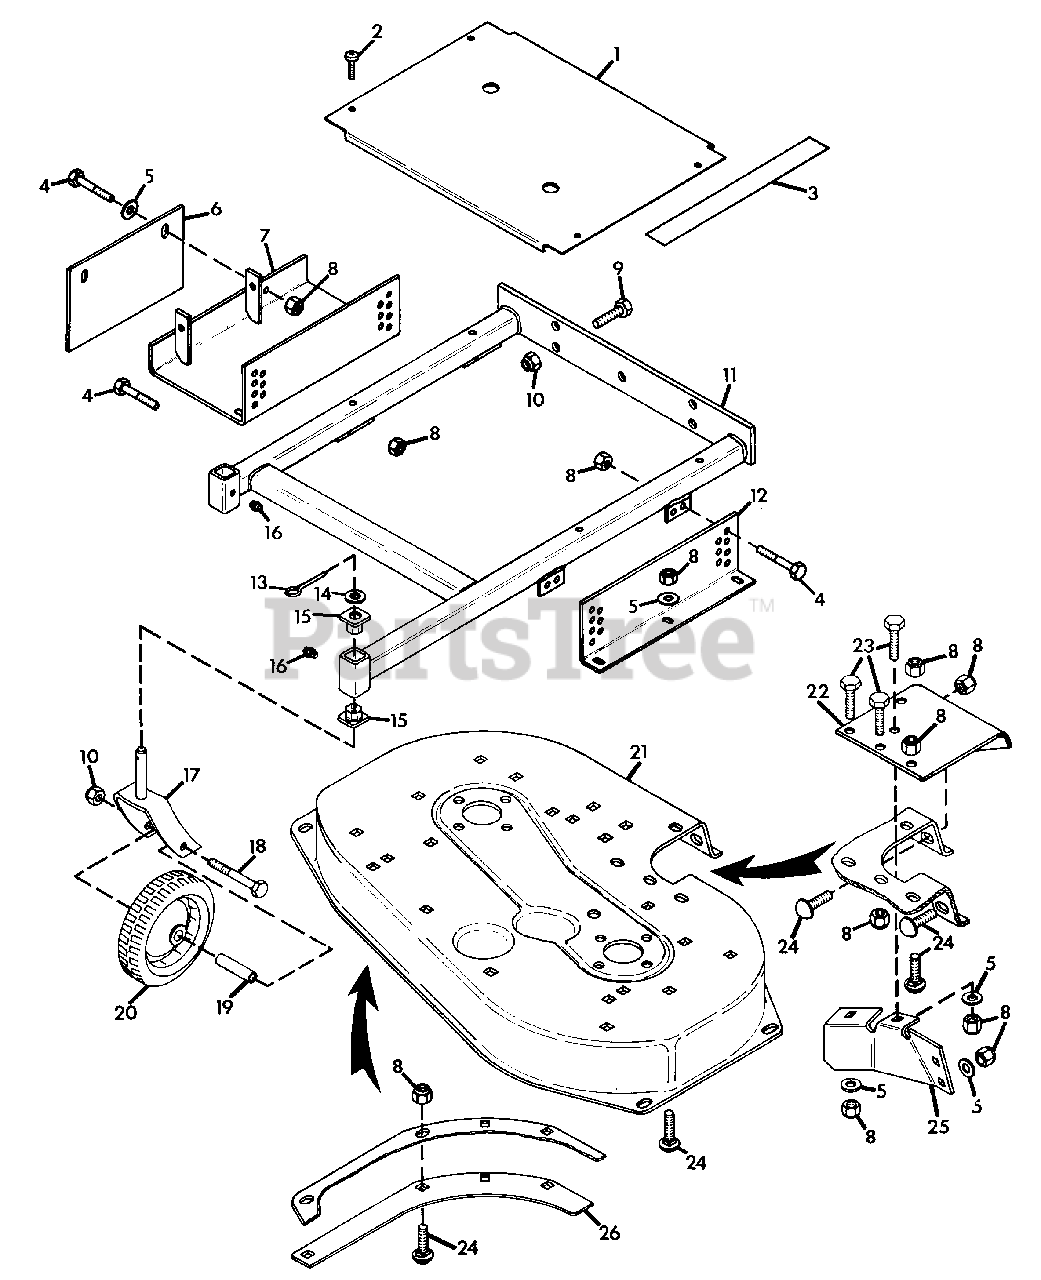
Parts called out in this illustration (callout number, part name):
1	GUARD, 40" MOWER BELT
2	SCREW, TAPPING 1/4-20X.50 P/HD
3	TAPE, VINYL FOAM(75' ROLL)
4	BOLT, HEX 3/8-16X1.00
5	WASHER, FLAT .406X.812X.065
6	PLATE, DISCHARGE COVER
7	WELDMENT, MOWER SUPPORT
8	NUT, LOCK 3/8-16
9	BOLT, HEX 1/2-13X1.50
10	NUT, LOCK 1/2-13
11	WELDMENT, FRAME SUPPORT
12	BRACKET, MOWER SUPPORT
13	PIN, COTTER .187X1.50
14	WASHER FLAT .813X1.37X.100
15	BEARING, FLANGED
16	FITTING, LUBE 1/4-28
17	WELDMENT, CASTER FORK
18	BOLT, HEX 1/2-13X5.00
19	BUSHING, WHEEL .520X.750X3.312
20	WHEEL, GAUGE
21	DECK, 40" MOWER
22	SHIELD, DISCHARGE
23	BOLT, HEX 3/8-16X1.25
24	BOLT, 3/8-16X1.00 RD HD SQ NK
25	SHROUD, BLADE
26	PLATE
NS	DECAL, CAUTION
NS	DECAL, DANGER HAND
NS	DECAL, DANGER FOOT
NS	DECAL, WARNING EYE
NS	DECAL, GRAVELY LOGO
